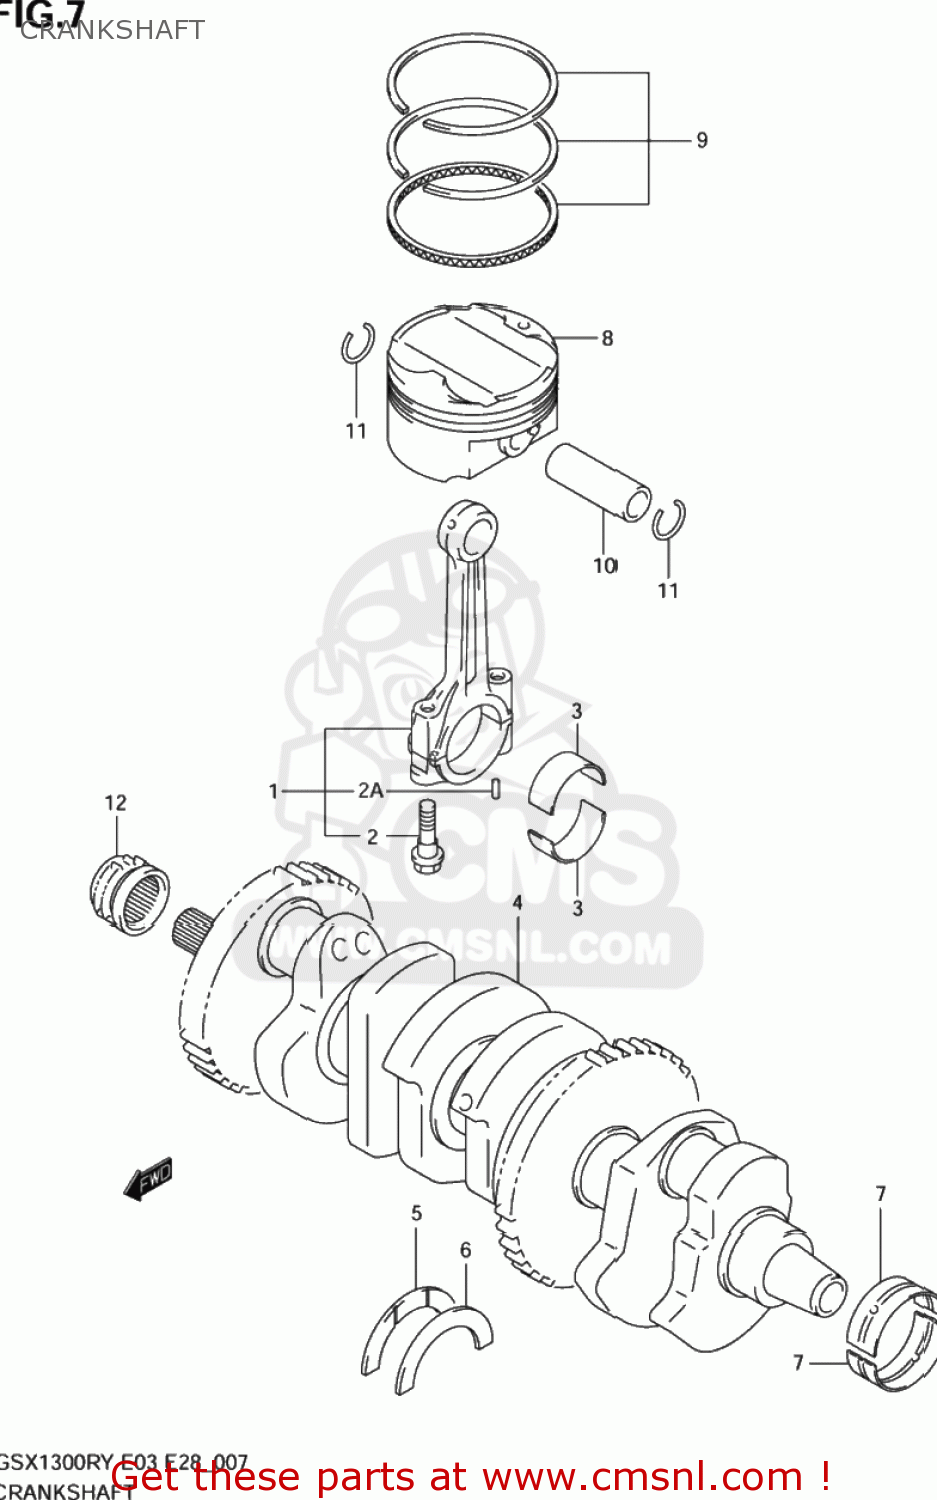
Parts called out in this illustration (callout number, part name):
1	CONNECTING ROD ASSY
2	BOLT,CONNECTING ROD
2A	PIN,CONNECTING ROD
3	BEARING,CRANK PIN
4	CRANKSHAFT SET
5	BEARING,CRANK THRUST,L
6	BEARING,CRANK THRUST,L
7	BEARING,CRANKSHAFT
8	PISTON
9	RING SET,PISTON
10	PIN,PISTON
11	CIRCLIP,PISTON PIN
12	SPROCKET,CAM CHAIN DRIVE
